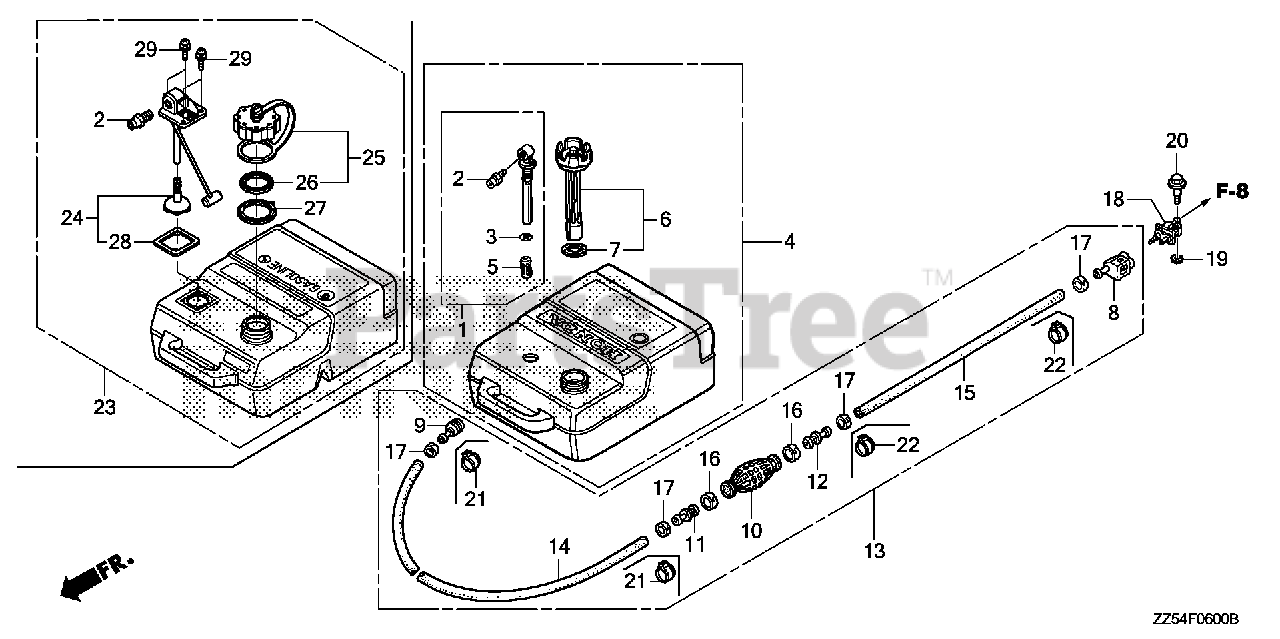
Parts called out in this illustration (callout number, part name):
1	JOINT ASSY., FUEL
2	FITTING, QUICK DISCONNECT
3	O-RING
4	TANK ASSY., FUEL
5	FILTER, FUEL
6	CAP, FUEL FILLER
7	GASKET, FUEL CAP
8	CONNECTOR ASSY., FUEL (A)
9	CONNECTOR, FUEL
10	BULB, PRIMER
11	VALVE, IN.
12	VALVE, OUTLET
13	TUBE ASSY., FUEL
13	TUBE ASSY., FUEL TANK
14	TUBE, FUEL LONG (7.3X2000)
15	TUBE, FUEL SHORT (6.3X500)
15	TUBE, FUEL SHORT
16	BAND, TUBE CLIP (20MM)
17	BAND, TUBE CLIP (12.5MM)
18	CONNECTOR ASSY., FUEL (B)
19	WASHER, PIVOT
20	BOLT, SPECIAL (6X22) (CT200)
21	CLAMP, FUEL TUBE
21	CLAMP, FUEL TUBE (14.0)
22	CLAMP, FUEL TUBE
22	CLAMP, FUEL TUBE (14.0)
23	TANK ASSY., FUEL
24	FILTER KIT, FUEL
25	CAP, FUEL FILLER
26	GASKET, FUEL CAP
27	RETAINER, PRESSURE RELIEF
28	GASKET, FUEL PICK-UP
29	BOLT-WASHER (5MM) (SEAL)
